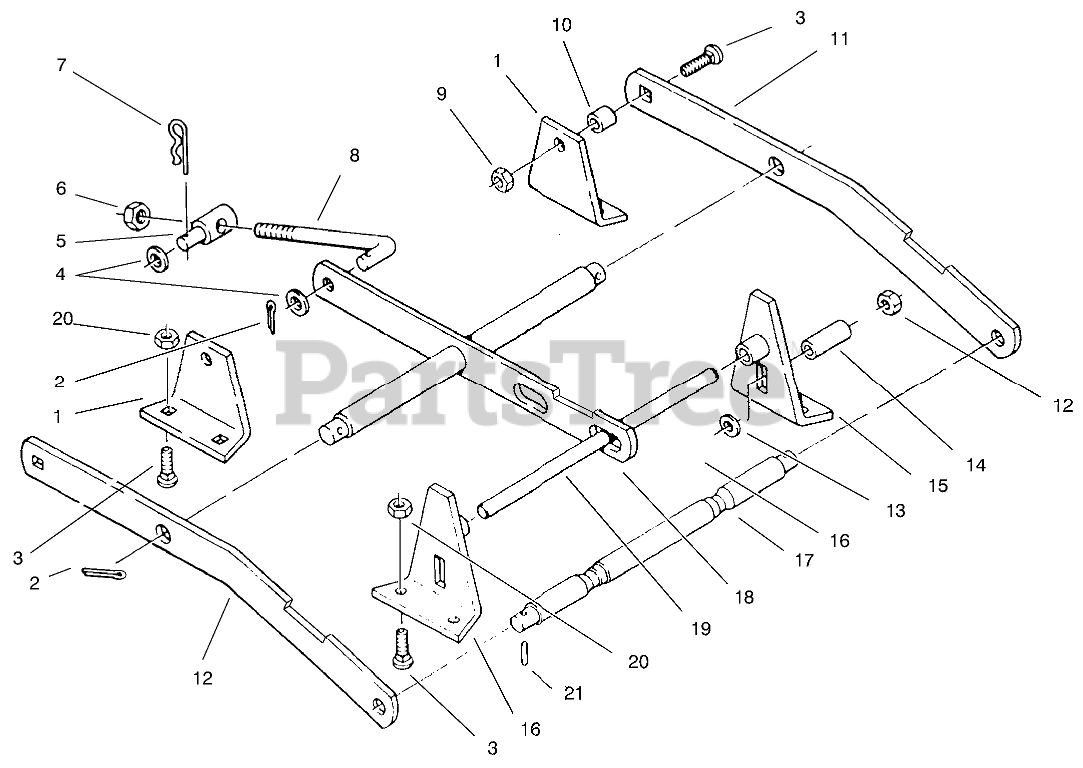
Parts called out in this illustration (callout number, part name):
1	Rear Deck Bracket
2	PIN-COTTER
3	BOLT-CARR
4	WASHER-FLAT
5	TRUNION
6	NUT-LOCK, NI
7	PIN-HAIR
8	ROD LEVELER
9	LOCKNUT-FLANGE
10	SPACER
11	Bar-Draft
12	NUT-LOCK, NI
13	WASHER-FLAT
14	SPACER
15	Front Deck Bracket
16	BOLT-CARR
17	Shaft
18	Leveler
19	Front Shaft
20	NUT-LOCK, NI
